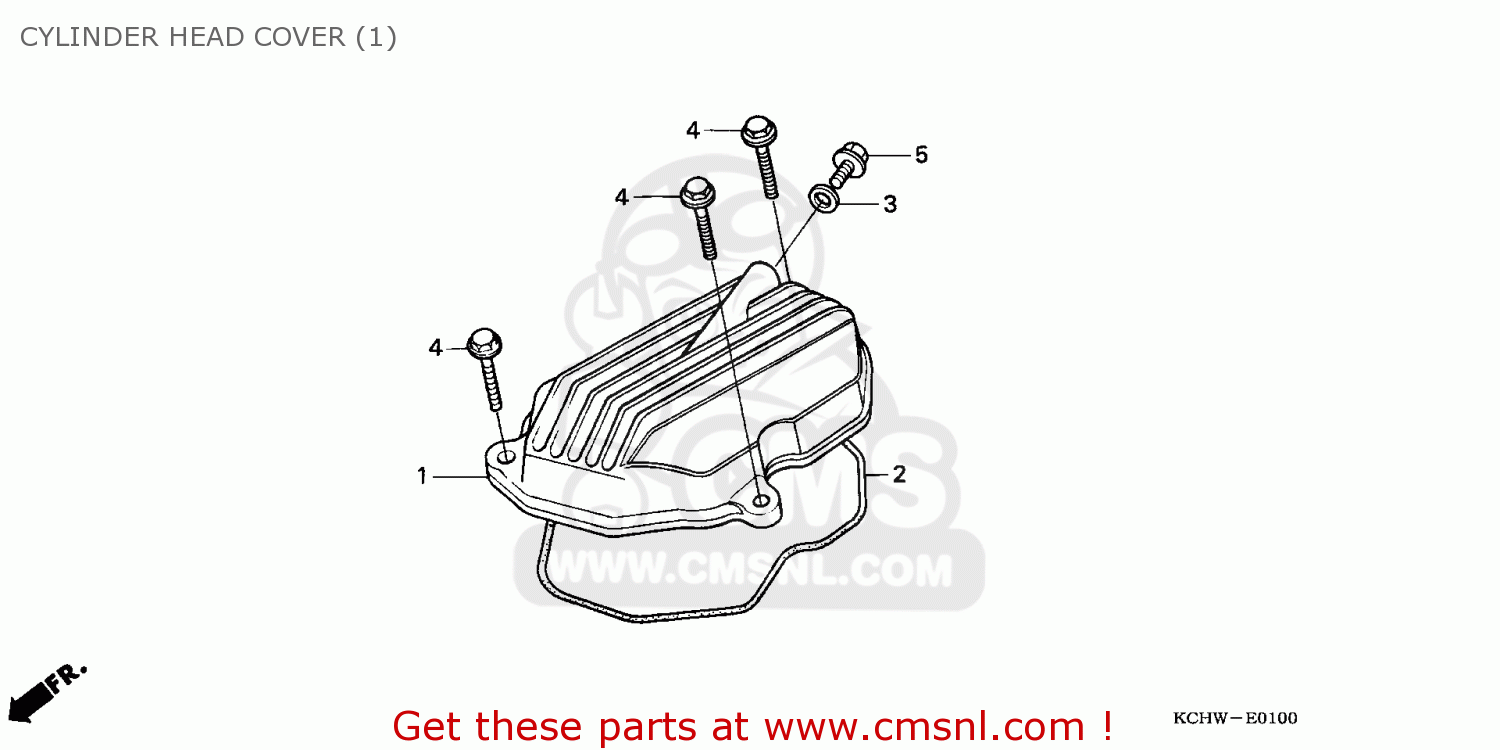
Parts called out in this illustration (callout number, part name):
1	COVER,CYLN HEAD
2	PACKING,CYLN.HEAD (NAS)
3	WASHER, SEALING
4	BOLT,FLANGE,6X28
5	BOLT,FLANGE,6X12
